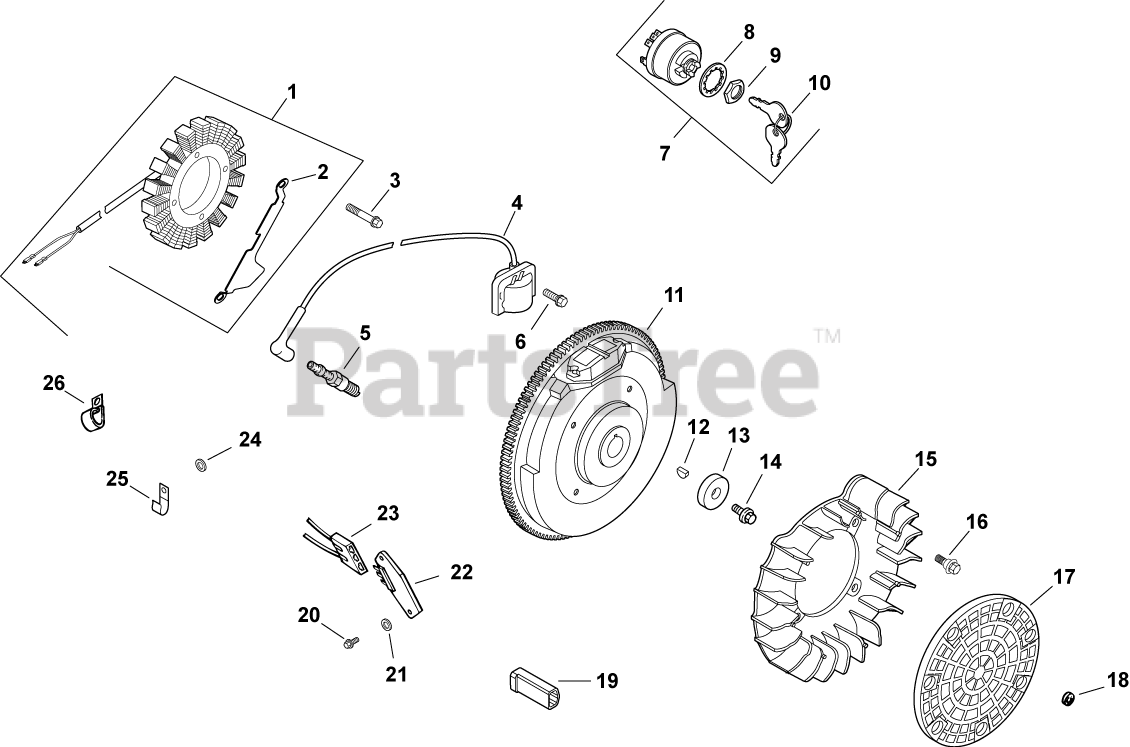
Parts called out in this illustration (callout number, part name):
1	STATOR KIT - USE 237878-S
2	BRACKET, STATOR WIRE
3	SCREW, M5X0.8X25 - (#25086402S)
4	MODULE, IGNITION-USE 24 584 45-S
5	PLUG, SPARK (STD)
6	SCREW, FLG THD FRM M5X.8X20-(#25086399S)
7	SWITCH ASSY, KEY (KM)-USE 25 099 32-S
8	WASHER, INTERNAL TOOTH
9	NUT, KEY SWITCH
10	KEY, SET -USE 48 340 01-S
11	FLYWHEEL, PAINTED-USE 24 025 55-S
12	KEY, 3/16" X 5/8"
13	WASHER, FLAT 13/32"
14	SCREW, FLG M10X1.5X45 - (#25086361S)
15	FAN (KM)-USE 24 157 15-S
16	BOLT, SHOULDER
17	SCREEN, GRASS
19	CONNECTOR (1 CONTACT)
20	SCREW, PHL HD #11-16X7/8"
21	WASHER, FLAT 3/16"
22	REG/RECT-15 AMP (KM)-USE 41 403 10-S
23	CONNECTOR, BODY (KM)-USE 25 155 41-S
24	WASHER, FLAT 1/4" (O.D. 1/2")
25	CLIP, CABLE
26	CLIP, TUBE & WIRING (KM)
